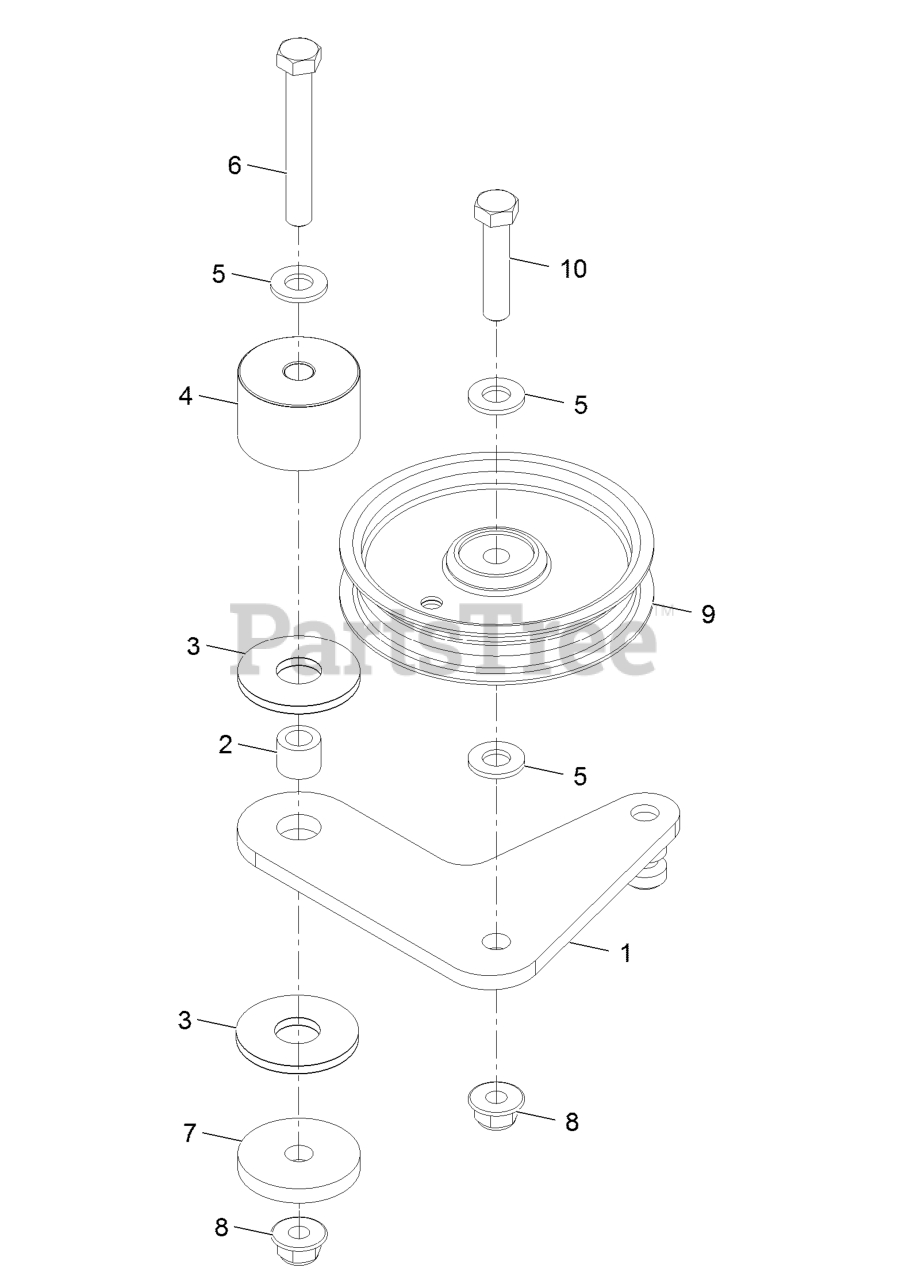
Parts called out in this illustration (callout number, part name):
1	PLATE-IDLER
2	BUSHING-LEVER, LIFT
3	WASHER-FRICTION, COMPOSIT
4	HUB, IDLER
5	WASHER-FLAT
6	SCREW-HH
7	WASHER-PLAIN
8	NUT-HF, NI
9	PULLEY-IDLER
10	SCREW-HH
